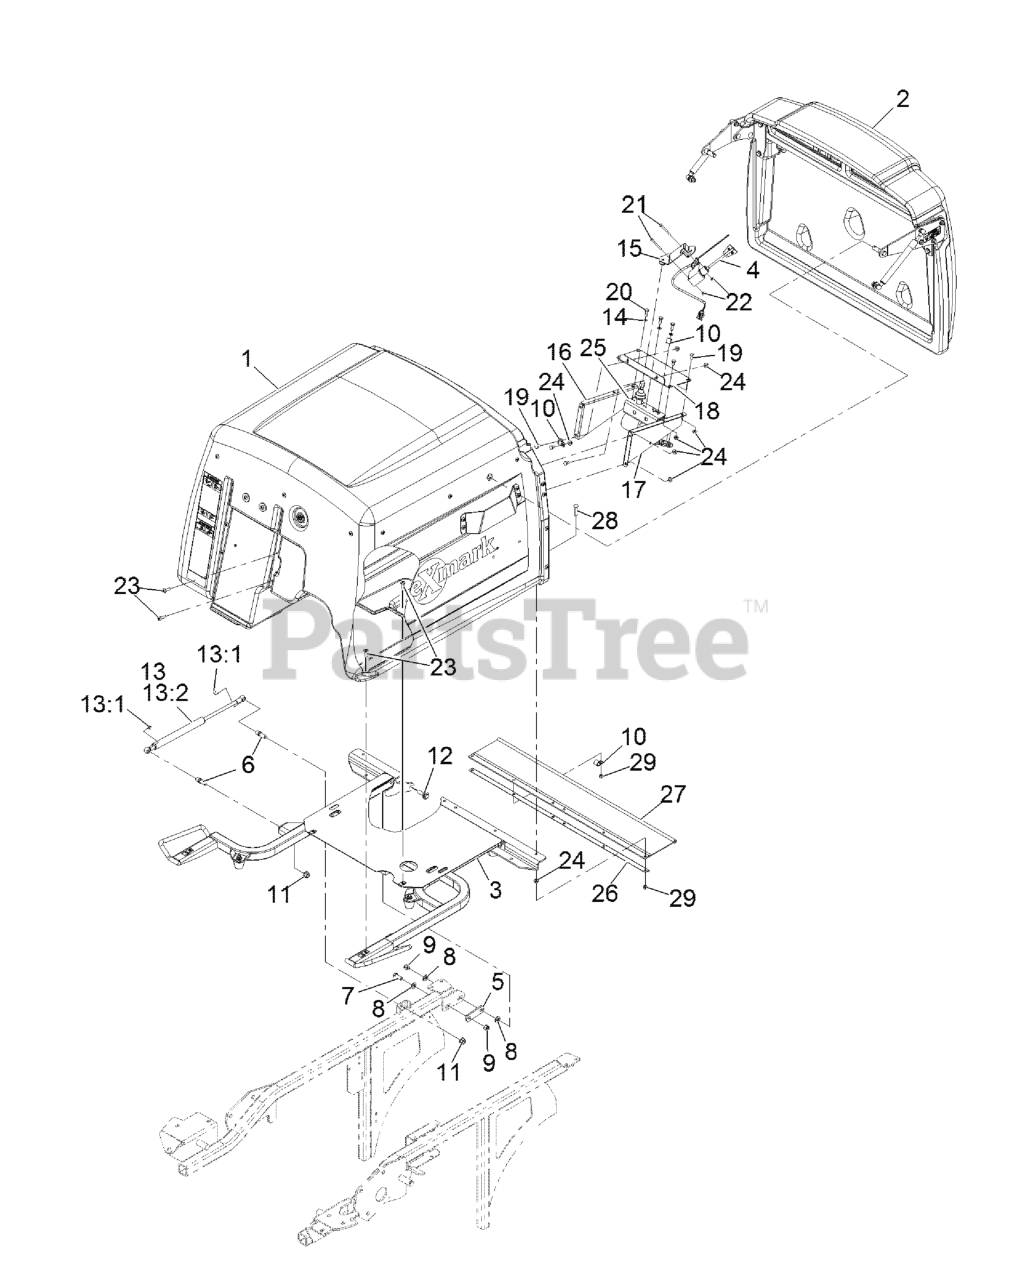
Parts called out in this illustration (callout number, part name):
1	ASM,HOPPER
2	ASM,DOOR HOPPER
3	HOPPER FRAME ASM
4	ASM,FILL SENSOR
5	ARM-LIFT, DECK
6	STUD-BALL
7	SCREW-HH
8	WASHER-FLAT
9	NUT-LOCK, NI
10	CLIP-LOOM
12	SCREW-SHOULDER, HWH
13	DAMPER KIT
13:1	CLIP-RETAINER
13:2	SHOCK-COMPRESSION, GAS
14	WASHER-SPRING
15	MOUNT-SWITCH
16	BRACKET-DRIVE MOTOR, LH
17	BRACKET-DRIVE MOTOR, RH
18	PLATE-SWITCH
19	SCREW-HH
20	SCREW-HH
21	SCREW-PPH
22	NUT-LOCK, NI
23	SCREW-TTH
25	KIT,FILL SENSOR MOTOR
26	CHANNEL-FRAME, HOPPER
27	DEFLECTOR-GRASS
28	SCREW-CARR
29	NUT-LOCK, NI
